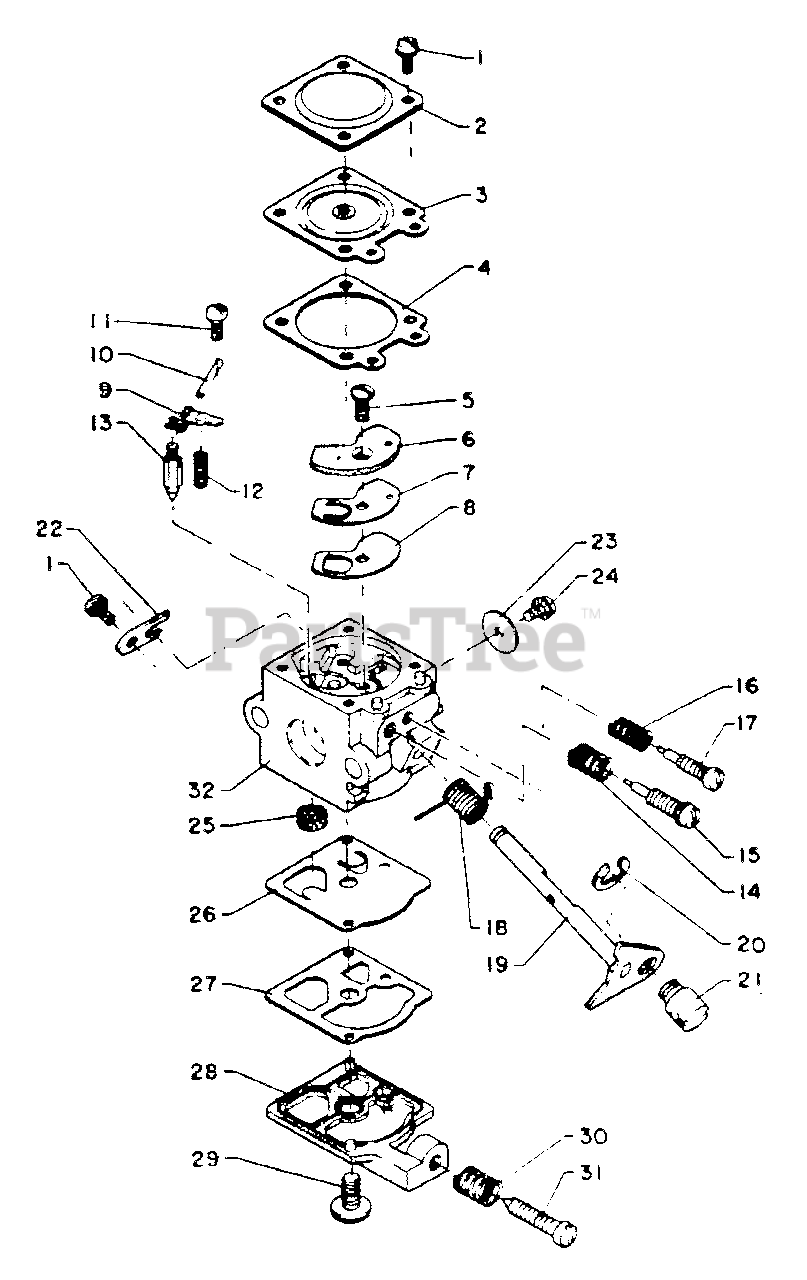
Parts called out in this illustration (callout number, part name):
1	CARBURETOR WA-80
2	COVER, METERING
3	DIAPHRAGM, METERING
4	GASKET, METERING
5	SCREW, CIRCUIT PLATE
6	PLATE, CIRCUIT
7	VALVE, CHECK
8	GASKET, CIRCUIT PLATE
9	LEVER, METERING
10	PIN, METERING LEVER
11	SCREW, METERING LEVER PIN
12	SPRING, METERING LEVER
13	VALVE, INLET NEEDLE
15	NEEDLE - HIGH SPEED
16	SPRING, IDLE ADJUST
17	NEEDLE - LOW SPEED
18	SPRING, THROTTLE RETURN
19	SHAFT, THROTTLE
20	RING, RETAINING
22	CLIP, THROTTLE SHAFT
23	VALVE, THROTTLE
25	STRAINER
26	DIAPHRAGM, PUMP
27	GASKET, PUMP
28	COVER, PUMP
29	SCREW, PUMP COVER
30	SPRING, IDLE ADJUST
31	SCREW, IDLE ADJUST
32	BODY, CARBURETOR
